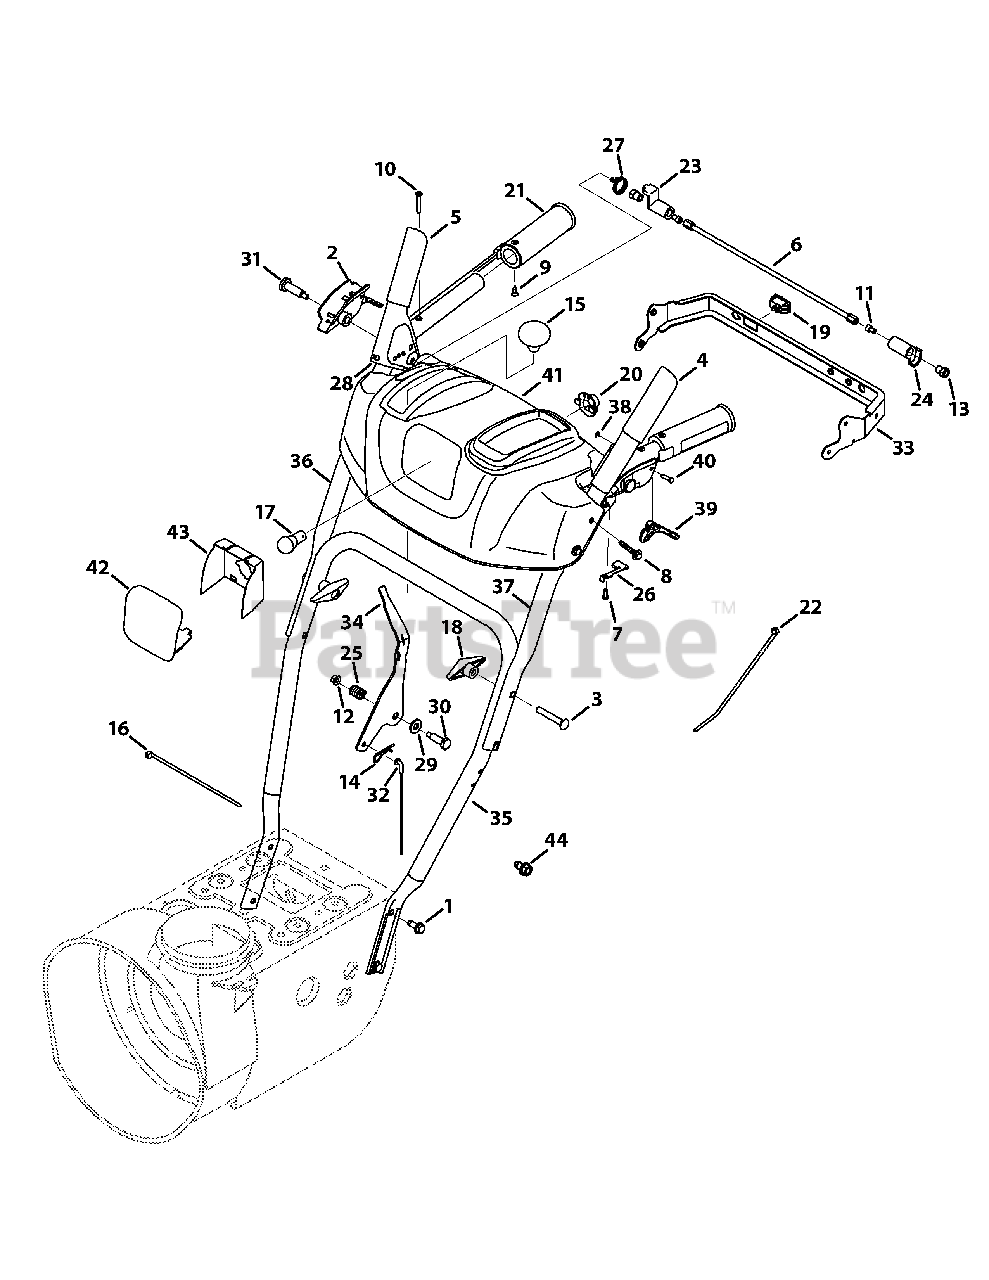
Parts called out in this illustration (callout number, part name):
1	Screw, Taptite, 5/16-18 x .750
2	Clutch Lock, RH
2	Clutch Lock, LH
3	Screw, Carriage, 5/16-18 x 2.50
4	Auger Engage, Red, LH
5	Drive Engage, Red, RH
7	Screw, Plastite, 8-16 x .50
8	Screw, Taptite, 1/4-20 x 1.625
9	Screw, 10-16 x 0.625
10	Screw, 10-24 x 1.375
11	Screw, 1/4-20 x .50
12	Nut, Flangelock, 1/4-20
13	Nut, Hex, 1/4-20
14	Click Pin, .092 x 1.64
15	Shift Knob
16	Cable Tie, 7"
18	Wing Knob, 5/16-18
19	Heated Grip Switch
20	Lamp Socket
21	Heated Grip
22	Cable Tie, Push Mount
23	Plate, Lock
24	Cam, Clutch Lock
25	Compression Spring, .39 x .60 x .88
26	Clutch Lock Spring
27	Torsion Spring, 0.8156 x .3038
28	Rubber Bumper
29	Washer, Flat, .385 x .87
30	Screw, Shield, .374 x 1.05
31	Screw, Shoulder, .437 x 1.345 x 1/4-20
32	Speed Selector Cable
33	Panel Bracket
34	Shift Lever
36	Upper RH Handle
37	Upper LH Handle
39	Steering Trigger Control, Red
40	Steering Trigger Pin, 3/16
41	Handle Panel, Troy-Bilt
42	Lens Panel, Troy-Bilt
43	Lens Label, Troy-Bilt
44	Screw, TT, 1/4-20 x .500
